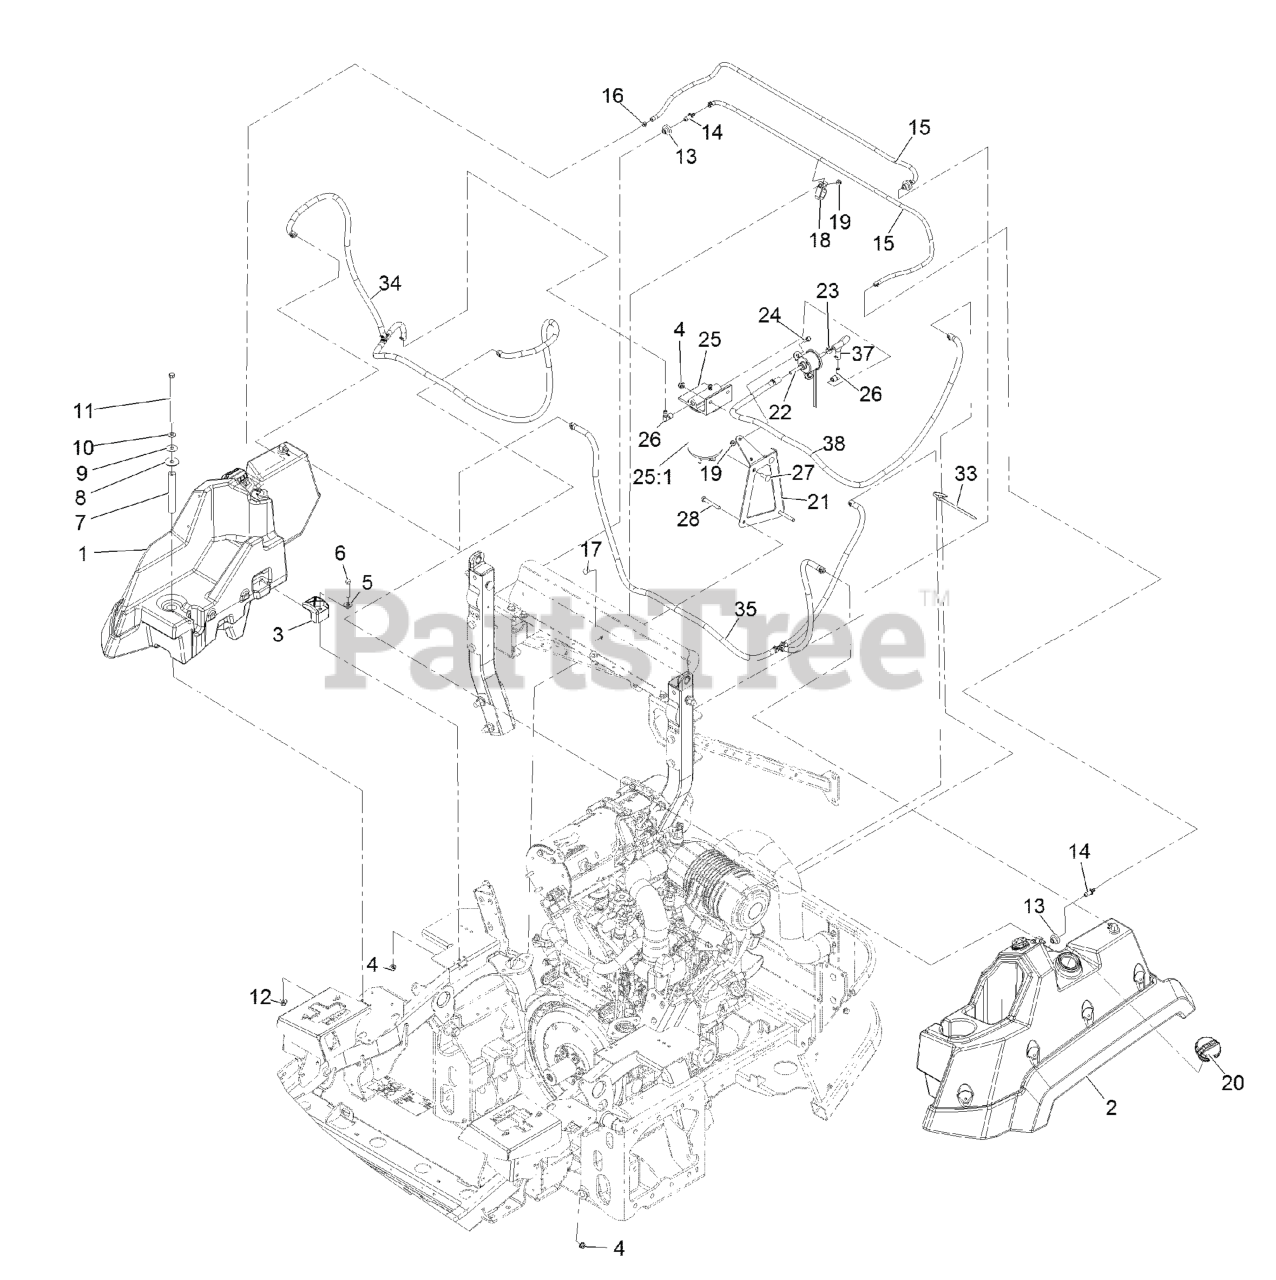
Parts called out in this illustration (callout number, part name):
1	RH FUEL TANK ASM
2	LH FUEL TANK ASM
4	NUT-HF, NI
5	WASHER-FLAT
6	SCREW-HH
7	TUBE-SPACER
8	WASHER-RUBBER
9	WASHER-PLAIN
10	WASHER-FLAT
11	SCREW-HH
12	NUT-HF, NI
13	BUSHING
14	FITTING-ORIFICE, STRAIGHT
15	HOSE-VENT, TANK
16	CLAMP-HOSE
17	SCREW-CARR
18	CLAMP-HOSE
20	CAP-FUEL, DIESEL
21	BRACKET-FILTER, FUEL
22	PUMP-FUEL, ELECTRIC
23	CLAMP-HOSE
24	SCREW-HWH
25	SEPARATOR FILTER ASM
25	FILTER-WATER/FUEL SEPERATOR
25:1	FILTER-FUEL/WATER SEPARAT
26	FITTING-HYD, 90
27	SCREW-CARR
28	SCREW-HH
33	TIE-PLASTIC
34	FUEL SUCTION LINE ASM
35	FUEL RETURN LINE ASM
37	HOSE-FUEL
38	HOSE-FUEL
